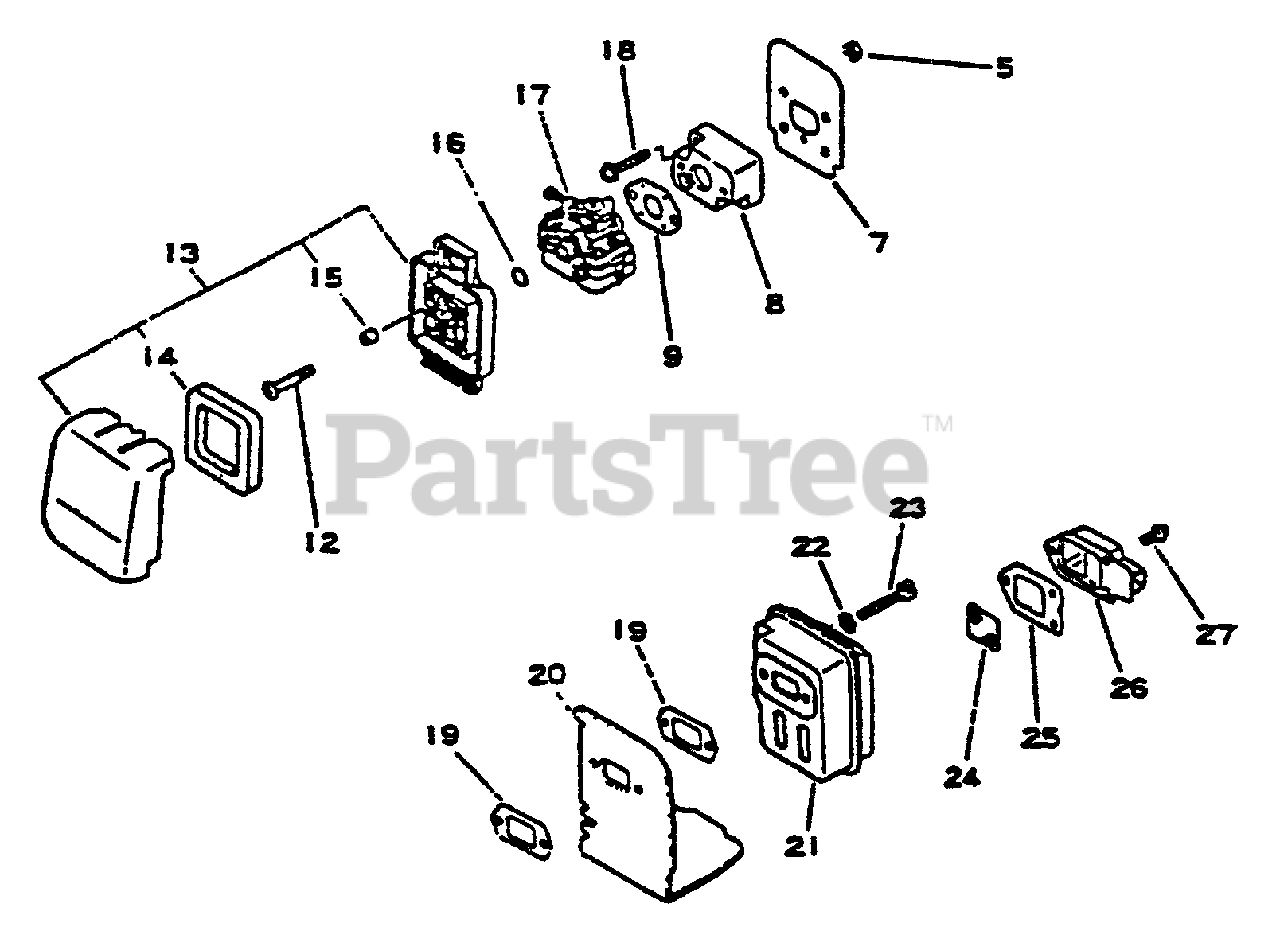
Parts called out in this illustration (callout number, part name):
5	NUT M5
7	HEAT SHIELD, INTAKE
8	INSULATOR, INTAKE
9	GASKET, INTAKE
12	SCREW 5×64
13	FILTER ASSY, AIR
14	FILTER, AIR
15	SLEEVE
16	O-RING 15
17	CARBURETOR - WYL-6
17	CARBURETOR - WYL-1
18	SCREW 5×22
19	GASKET, EXHAUST
20	COVER, EXHAUST
21	MUFFLER
22	WASHER, FLAT 5.5×10×0.8
23	BOLT 5×55
24	SCREEN, SPARK ARRESTER
25	GASKET, EXHAUST
26	GUIDE, EXHAUST - INNER
27	SCREW 4×10
